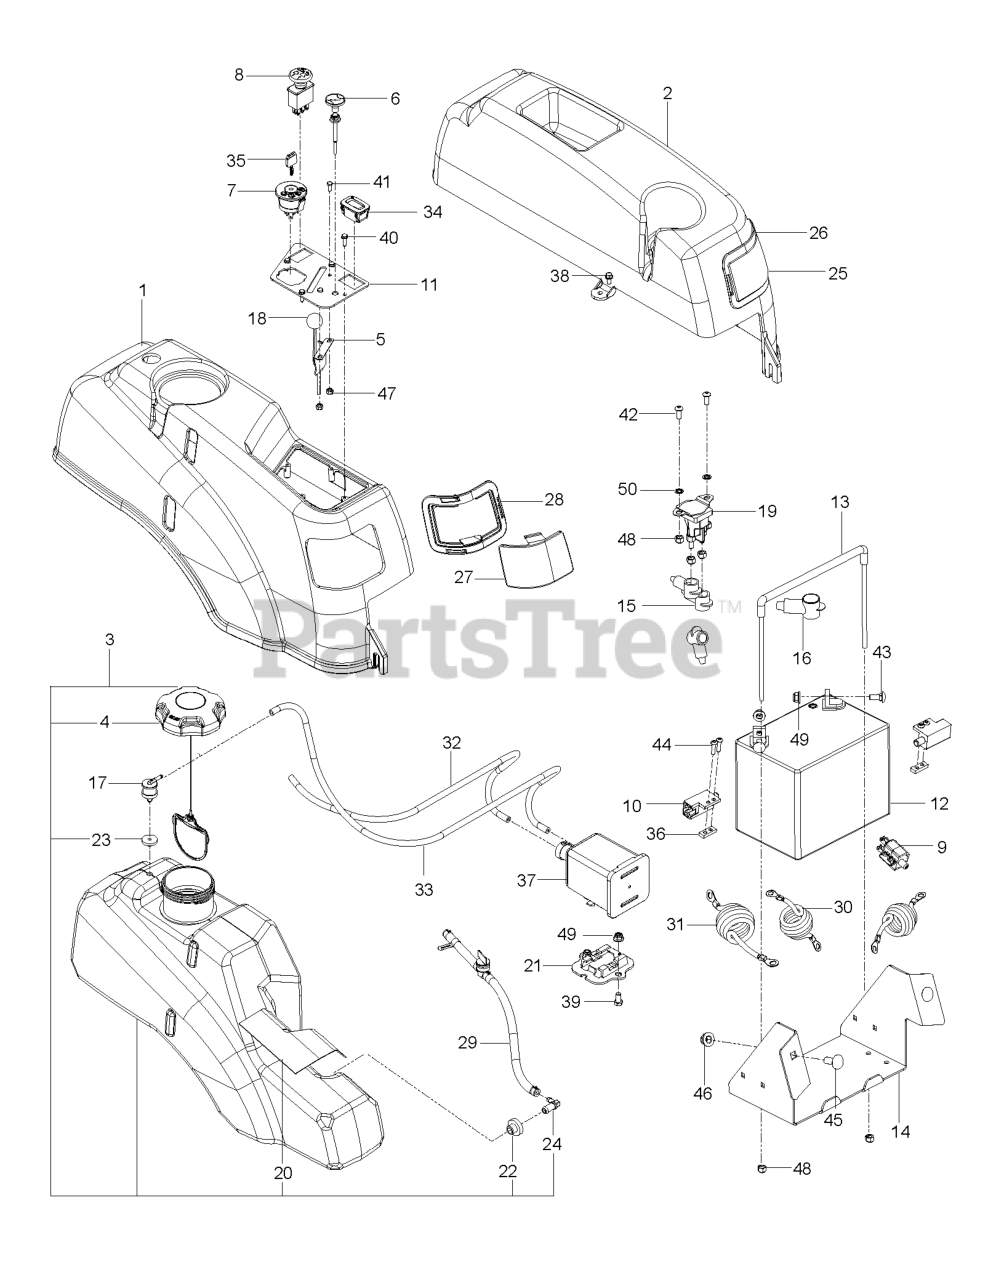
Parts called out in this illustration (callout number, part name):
1	FENDER, RT, GRAY
2	FENDER, LT
3	TANK.FUEL.ASSEMBLY.LARGE
4	CAP, FUEL
5	THROTTLE CABLE
6	CHOKE CABLE
7	RP IGNITION SWITCH
8	RP.SWITCH, BLADE
9	SWITCH, BRAKE 3P
10	SWITCH, INTERLOCK
11	CONSOLE.PLATE.BLACK
12	BATTERY, 12 V 330 AMP
13	BATTERY TIE DOWN ASSEMBLY
14	BOX, BATTERY, BLACK
15	TERMINAL COVER-SM
17	VALVE.FUEL.CHECK
18	KNOB.ROUND.BALL.BLACK
20	SHIELD, HEAT
21	BRACKET, CANISTER
22	RUBBER GROMMET
23	GROMMET, CHECK VALVE
24	STEM, FUEL TANK
25	LENS, COLORED LEFT
26	LEFT HEADLIGHT RIM GREY
27	LENS, COLORED RIGHT
28	RT HEADLIGHT RIM GREY
29	FUEL LINE ASSY
30	CABLE POSITIVE, LONG
31	BATTERY CABLE, NEGATIVE
32	HOSE, VAPOR 3/16 X 30"
33	HOSE, VAPOR 3/16 X 39"
34	RP.GUAGE.SRVCMNDR.HRMTR.
35	KEY MLD GEN DELTA
36	TAPPED PLATE
37	CANNISTER, CARBON
38	SCREW
39	HCS 5/16-18 X 5/8 GR 5 ZD
40	SCR #10-12X3/4 HEX WAS HD ZD
41	HCS #10-24 X 1/2
42	SCR 1/4-20 X 5/8 BTN SKT HD ZD
43	RP BOLT 5/16-18 X3/4 ZN/YEL GR
44	SCR #10-24 X .75 SKT HD BLK
45	RHSNB 3/8C X 1
46	NUT 3/8-16 HEX FLG NYLOC ZD
47	NUT 10-24 NYLOC
48	NUT.1/4-20.HEX.NYLOC.ZD
49	5/16-18 NYLOC FLANGE NUT
50	WASHER 1/4 INT TOOTH
